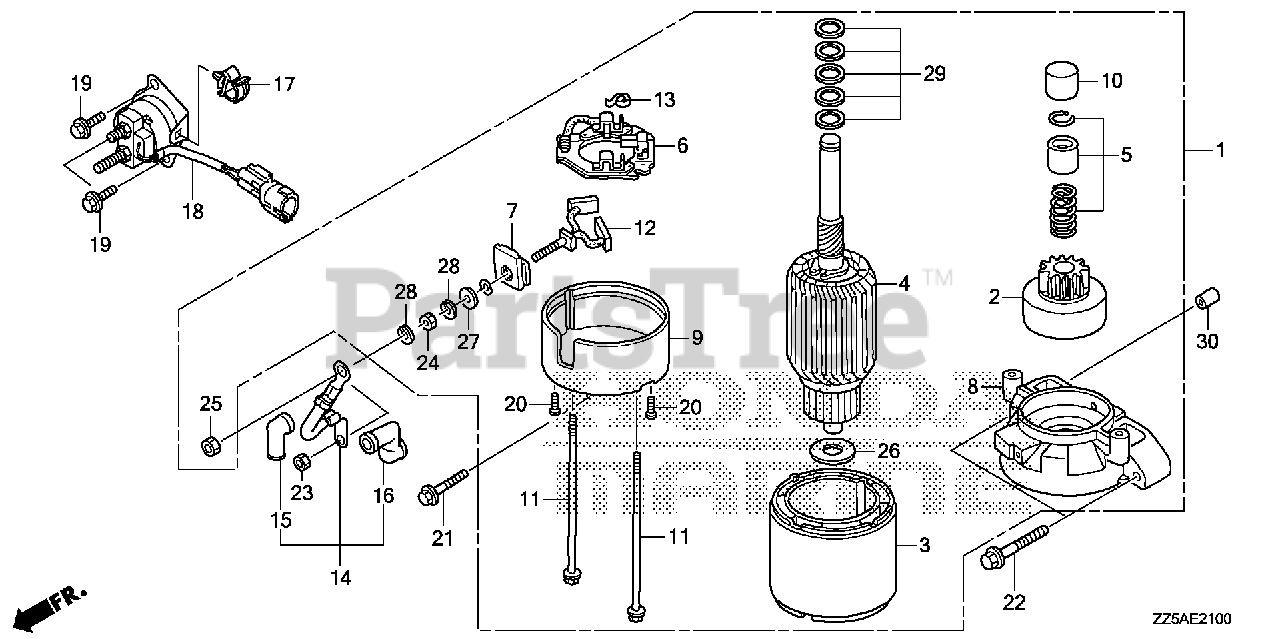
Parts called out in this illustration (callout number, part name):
1	STARTER MOTOR ASSY.
2	CLUTCH, OVERRUNNING
5	STOPPER SET, PINION
6	HOLDER, BRUSH
8	BRACKET, FR.
9	BRACKET, RR.
10	CAP, STOPPER
11	BOLT, THROUGH
13	SPRING, BRUSH
14	WIRE, MAGNETIC SWITCH
15	COVER, STARTER MOTOR TERMINAL
16	COVER, MAGNETIC SWITCH
17	CLAMP, WIRE
18	SWITCH ASSY., STARTER MAGNETIC
19	BOLT, FLANGE (6X14) (CT200)
20	SCREW (4MM)
21	BOLT, FLANGE (6X28)
22	BOLT, FLANGE (8X45)
23	NUT, HEX. (6MM)
26	WASHER, RR.
27	WASHER (1)
28	WASHER (2)
29	WASHER SET, THRUST
30	PIN, DOWEL (10X16)
